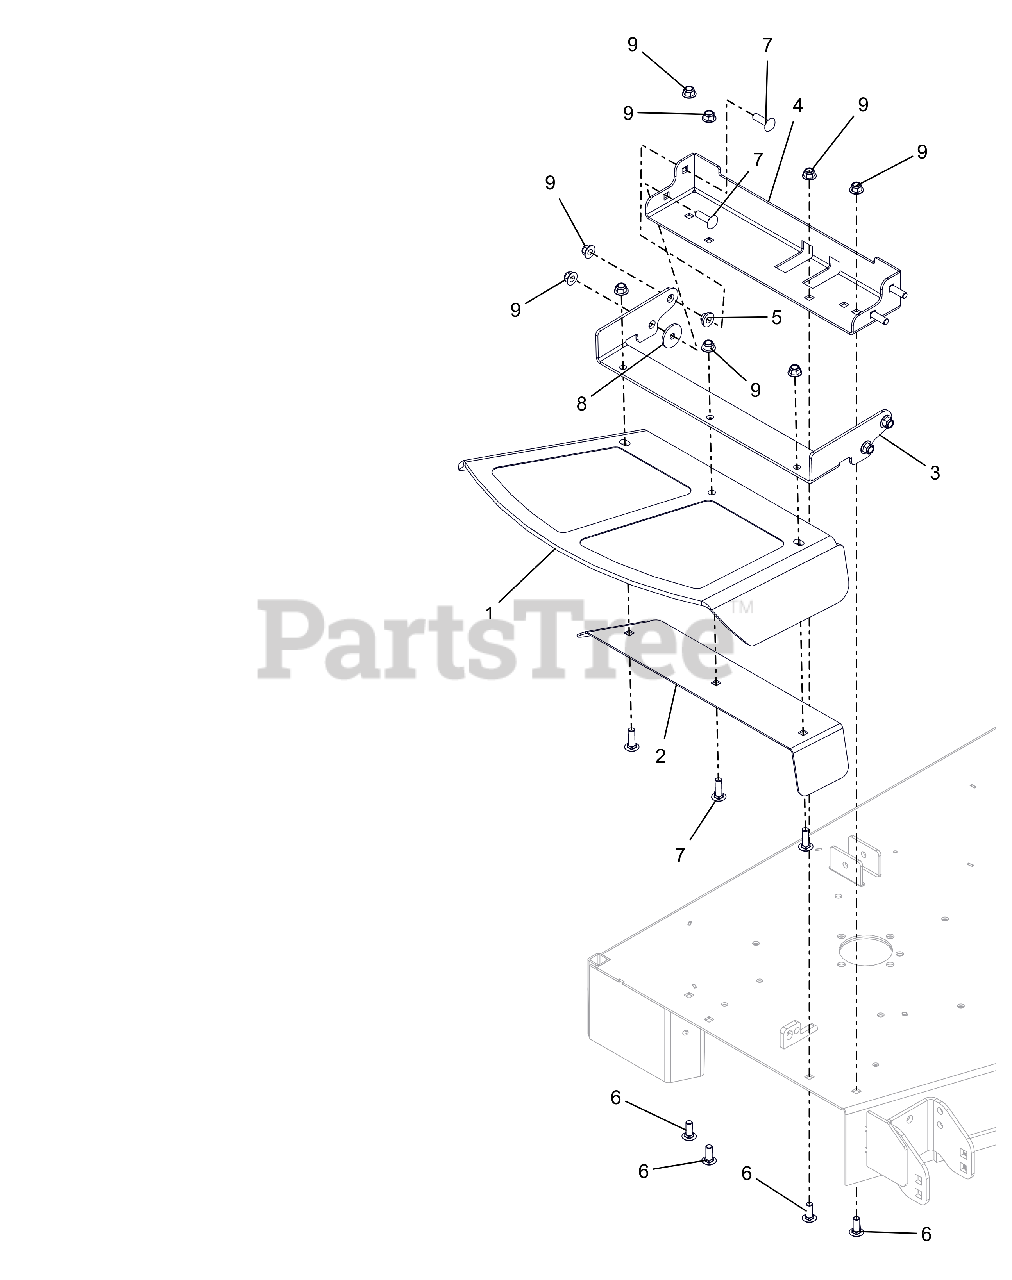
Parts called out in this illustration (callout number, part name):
1	CHUTE,48-60" FRMD RUBBER DISCH
2	PLT, DISCH. CHUTE CLMP-CE
3	BRKT, CE CHUTE MTG
4	WMT, DISCH. CHUTE-CE-W/SAFETY
5	BSHG-FLG .385X.500X.875X.406
6	BLT,RHSSN .38-16X1.00 G5 ZCC
7	BLT,RHSSN .38-16X1.25 G5 ZCC
8	WSHR, FLT .380X1.50X.125 ZCC
9	NUT,NYL-FLG .38-16 GF ZCC
